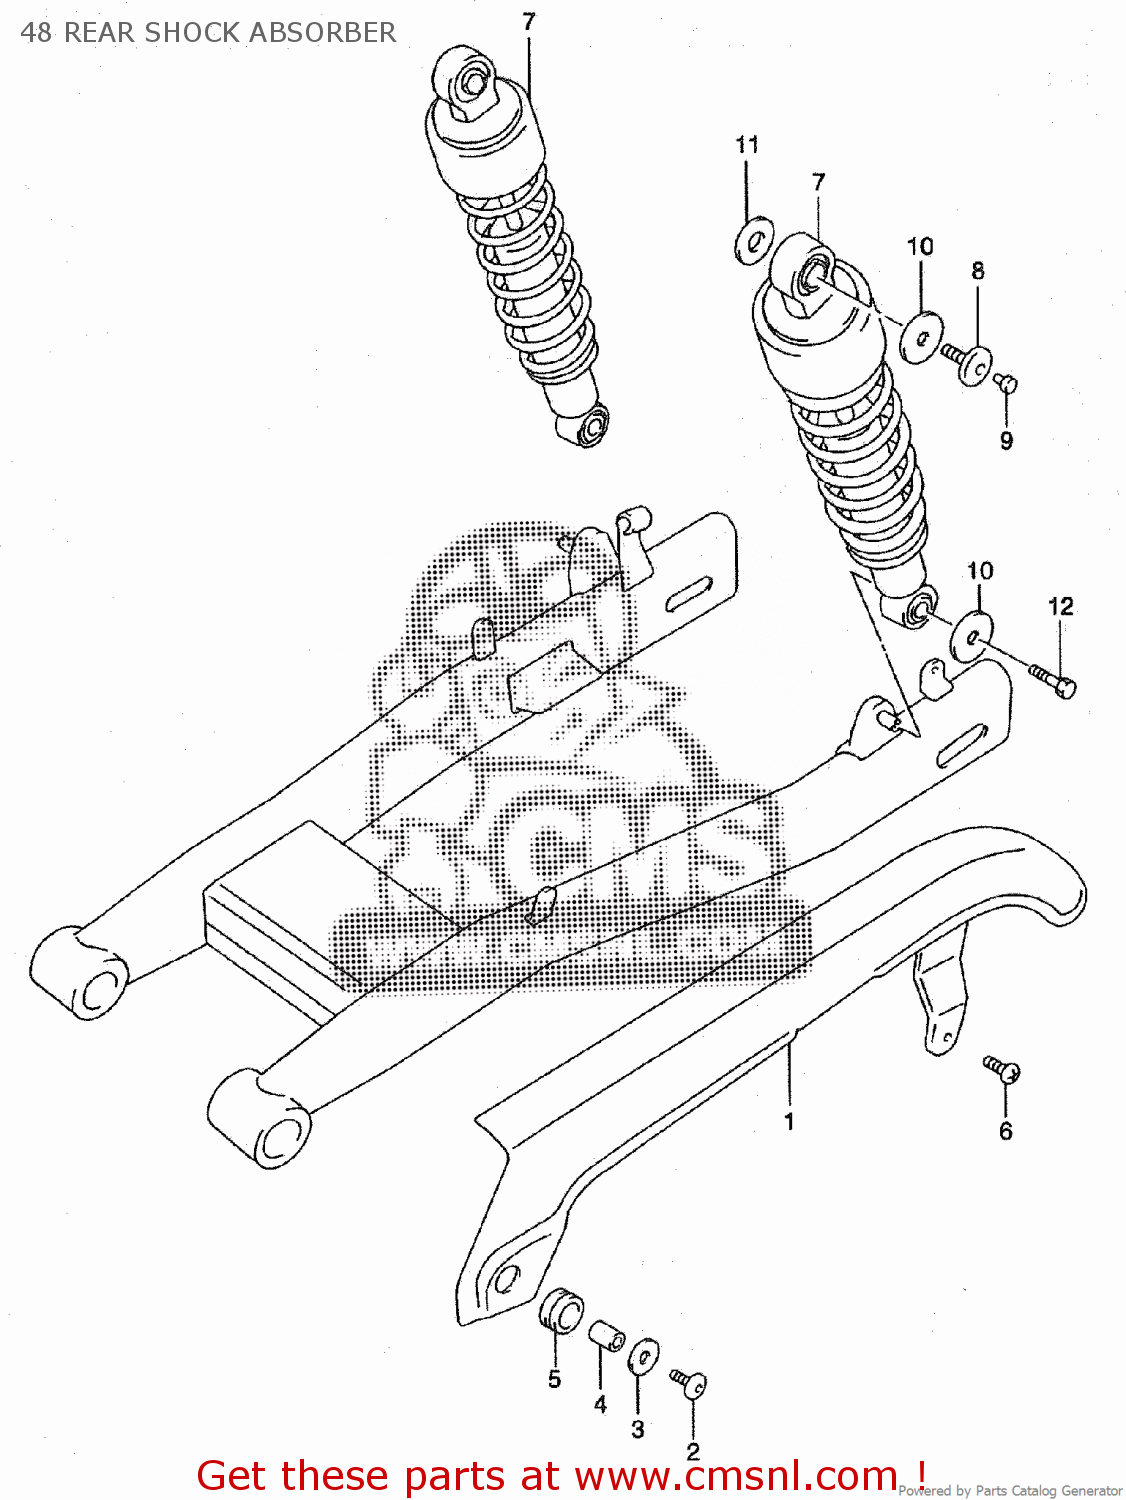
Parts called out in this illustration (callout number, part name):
1	CASE,CHAIN
2	SCREW(6X16)
3	WASHER(6.5X20X1.2)
4	SPACER(6.5X9X7)
5	CUSHION
6	SCREW(6X16)
8	BOLT(8X20)
9	CAP(OD:11)
10	WASHER (8.5X30X2.3)
11	WASHER(14.5X29X2.3)
12	BOLT
